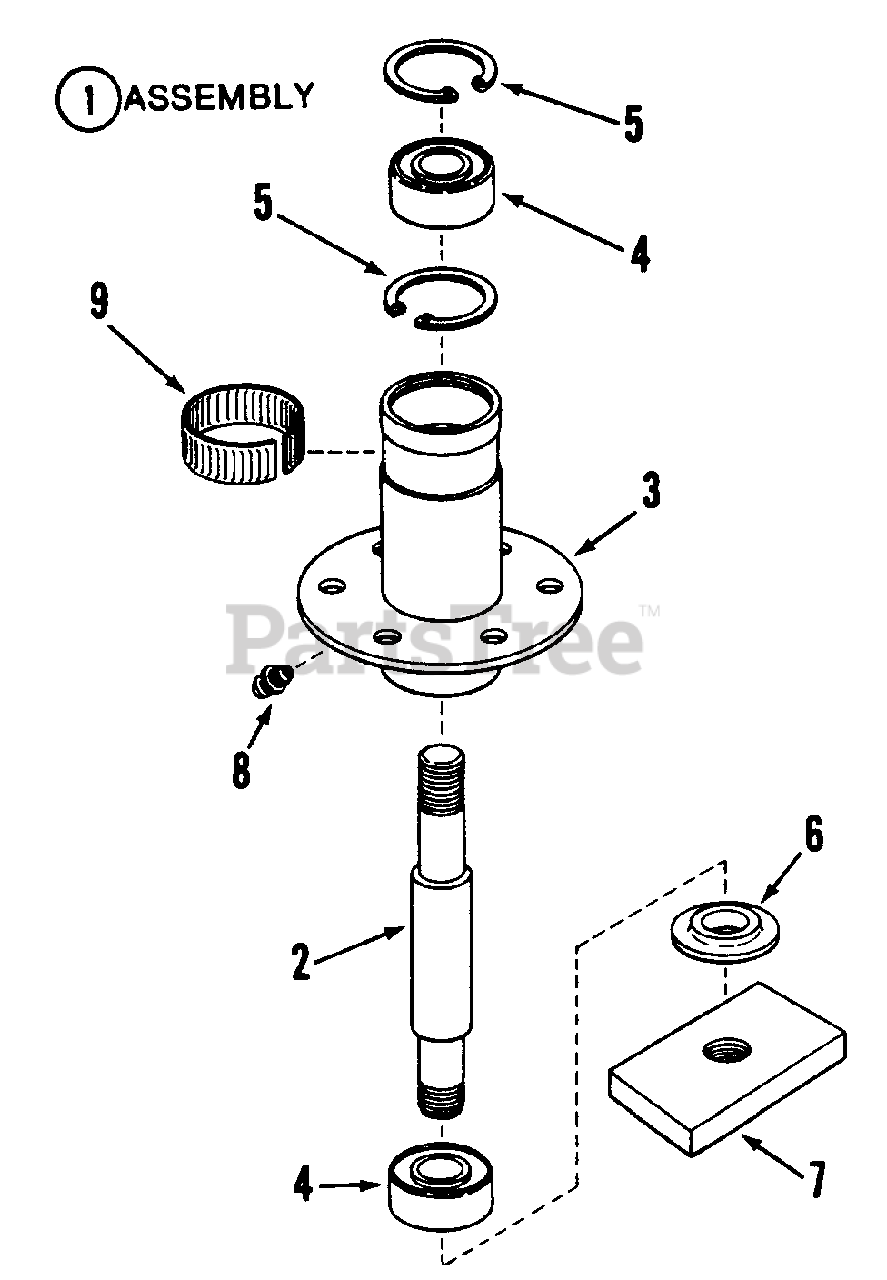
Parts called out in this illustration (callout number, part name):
1	ASSEMBLY, Spindle
2	SPINDLE, 7.25"
3	HOUSING, Spindle
4	BEARING, Spindle
5	RING, Retaining
6	WASHER, Spindle
7	HOLDER, Blade
8	FITTING, Lube (Press fit for .187 hole-no ball)
9	RING, Tolerance
